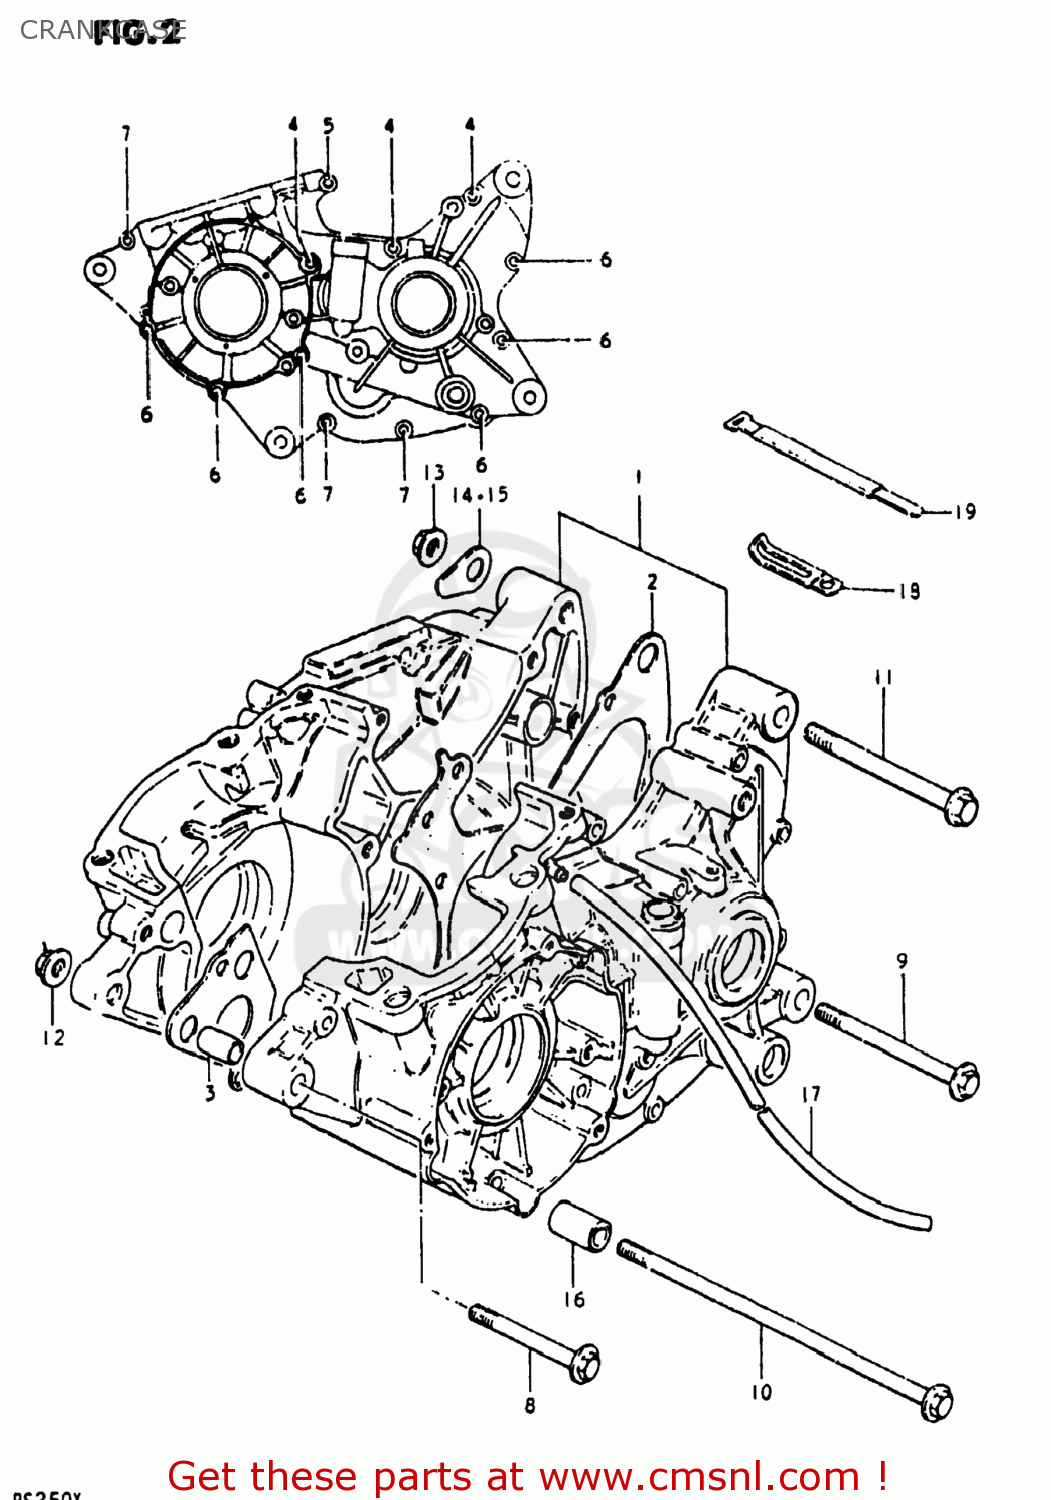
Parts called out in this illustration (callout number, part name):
1	CRANKCASE SET
2	GASKET,CRANKCASE (MCA)
3	PIN
4	SCREW 6X65
5	SCREW
6	SCREW
7	SCREW (6X35)
8	BOLT(8X67)
9	BOLT
10	BOLT
11	BOLT
12	NUT
13	NUT
14	WASHER
15	WASHER
16	SPACER(8.6X16X26)
17	HOSE
18	CLAMP
19	CLAMP L:110
